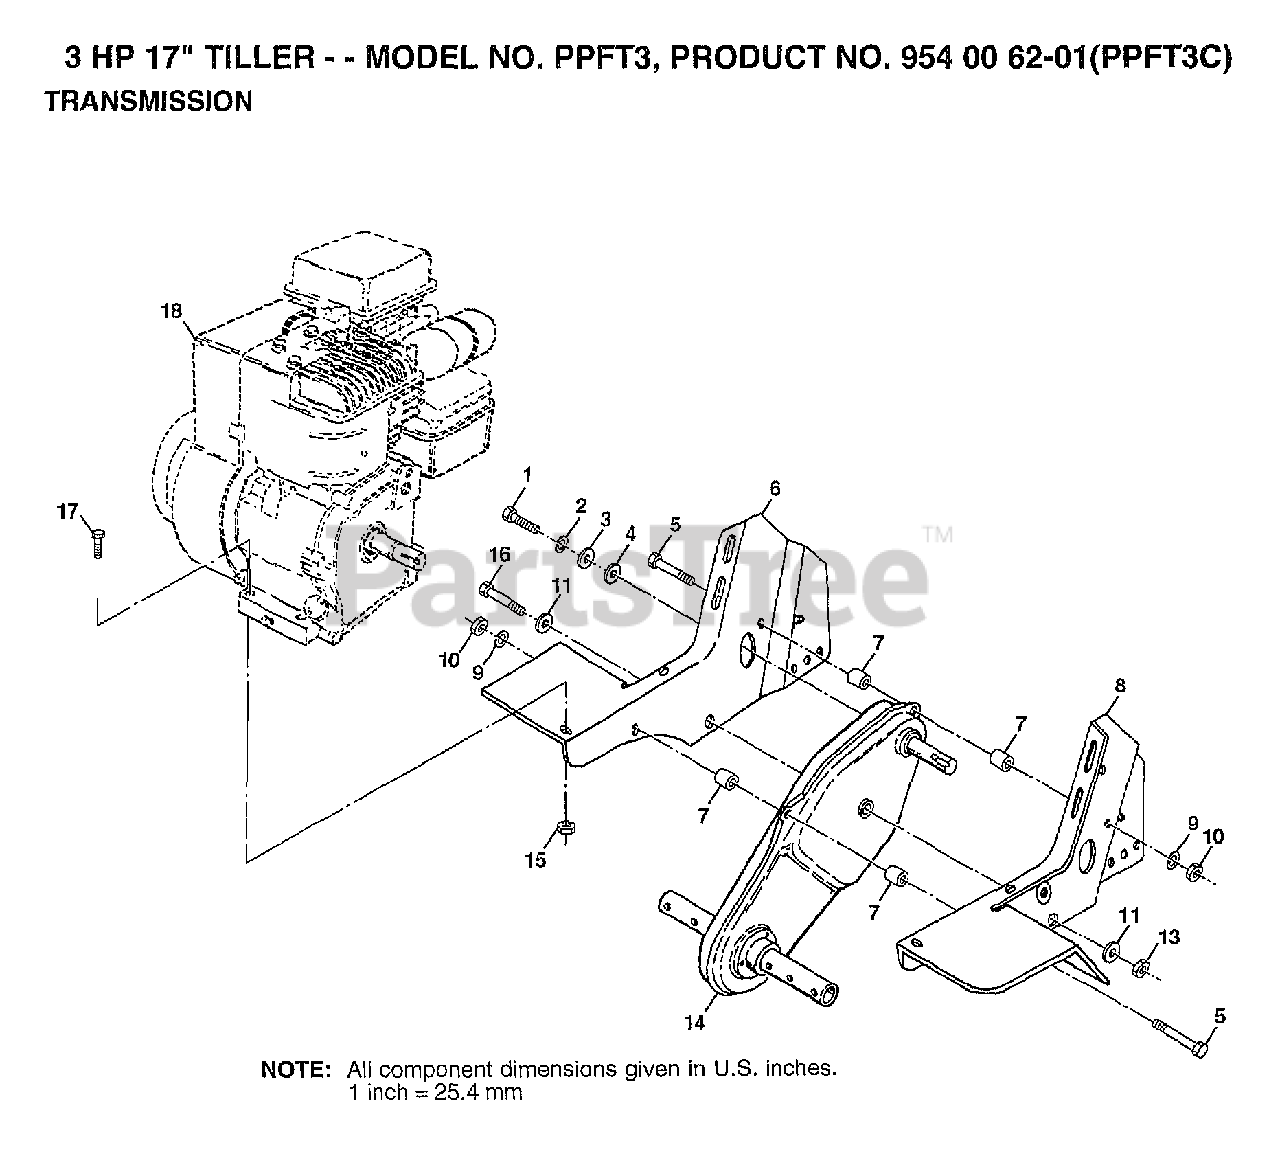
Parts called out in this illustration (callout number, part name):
1	BOLT, HEX 1/4-28 X 3/4 GR. 5
2	WASHER, LOCK 1/4
3	WASHER 9/32 X 1-1/4 X 16 GA.
4	WASHER 9/32 X 7/8 X 12 GA.
5	BOLT, HEX 5/16-18 X 2-3/4
11	WASHER 13/32 X 13/16 X 11 GA.
13	LOCKNUT
15	NUT, KEPS 5/16-18
16	BOLT, HEX 3/8-16 X 3-1/4
17	BOLT, HEX 5/16-18 X 1-1/2
